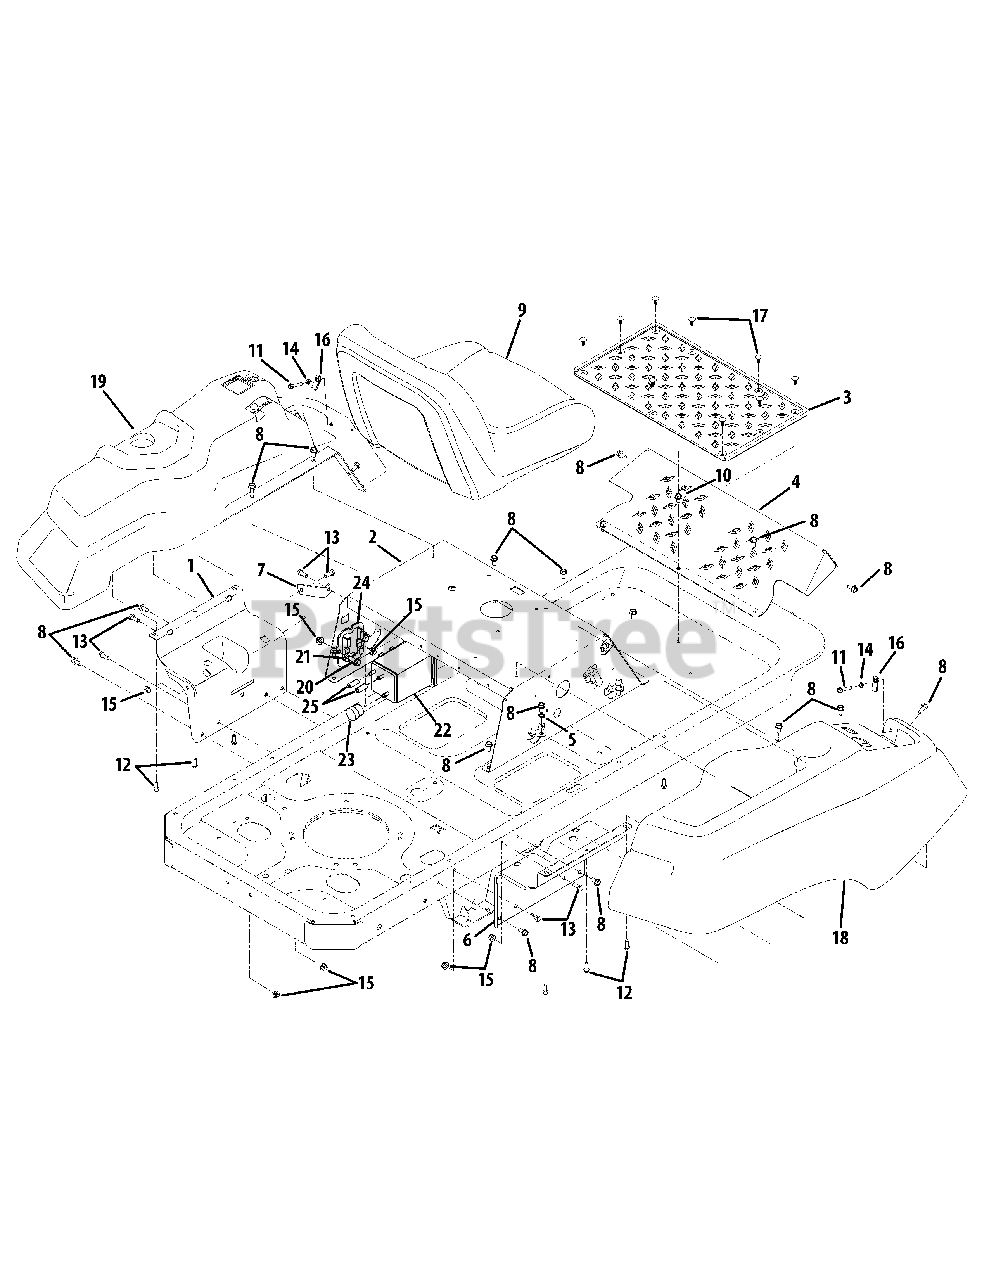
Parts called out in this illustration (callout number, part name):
1	Console Mount Bracket
3	Foot Pad
5	Lock Washer, 3/8
6	Console Mount Bracket
7	Fuel Tank Support Bracket
8	Hex Washer Screw, 5/16-18 x .750
9	High-Back Seat
10	Hex Washer Screw, 5/16-18 x .825
11	Hex Washer Screw, 1/4-20 x 1.500
12	Hex Washer Screw, 1/4-15 x .750
13	Hex Screw, 5/16-18 x .75
14	Jam Nut, 1/4-20
15	Flange Lock Nut, 5/16-18
16	U-Type Nut, 1/4-20
17	Ratchet Clip, .250
18	RH Console
19	LH Console
20	Hex Washer Screw, 5/16-18 x .875
21	Flat Washer, .344 x .750 x .120
22	Carbon Canister
23	Canister Filter Vent
24	Canister Adapter Bracket
25	Low Permeation Fuel Hose
